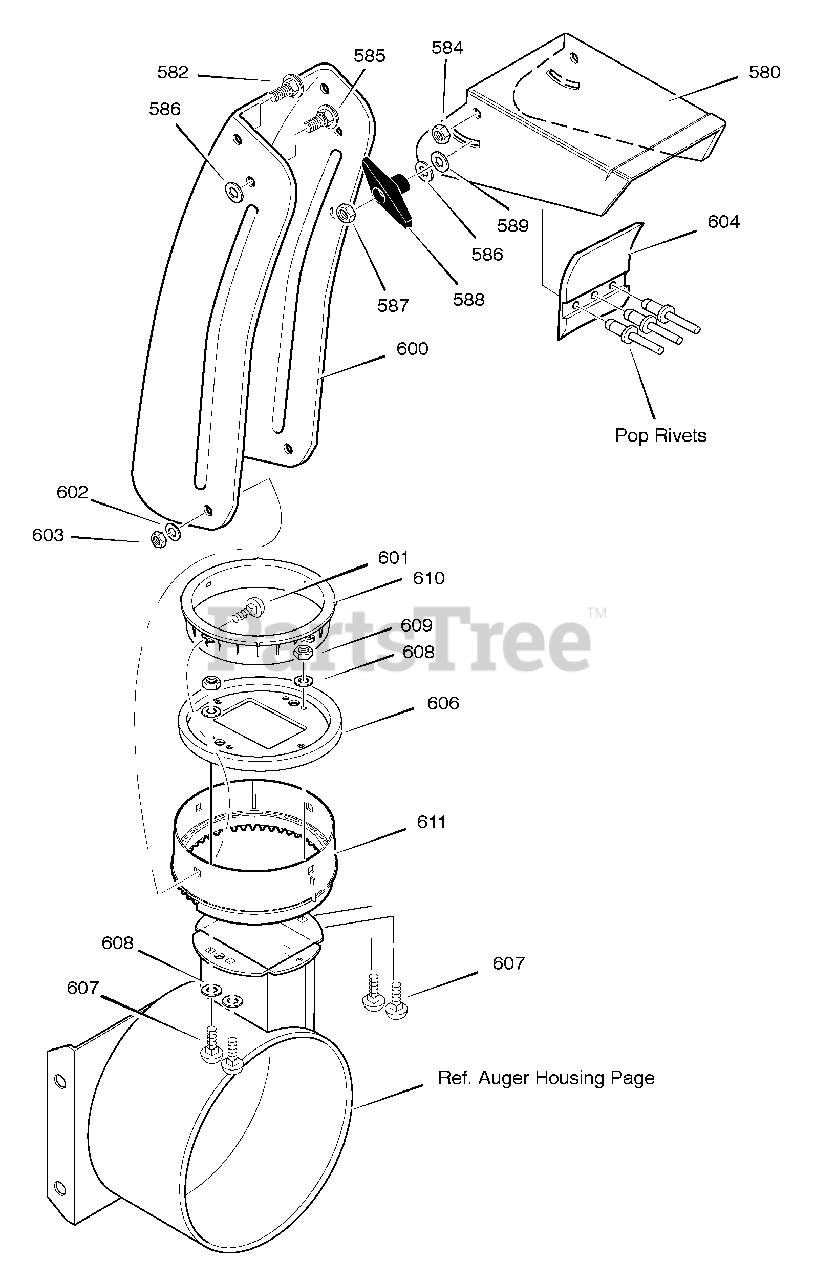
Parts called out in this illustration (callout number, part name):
580	CHUTE, UPPER
582	SCREW, 5/16-18 x 0.75
584	NUT, 5/16-18 HEX NYLOCK
585	BOLT, CAR, 5/16-18 X1.5
586	PLASTIC WASHER
587	NUT, 5/16-18 HEX
588	KNOB, T
589	PLASTIC WASHER
600	CHUTE, LOWER
601	BOLT, 5/16-18 x 1.00 CARRIAGE
602	WASHER, FLAT
603	NUT, 5/16-18 HEX NYLOCK
606	CHUTE COLLAR
607	BOLT, 1/4-20 x .75
608	WASHER, FLAT
609	NUT, 1/4-20 HEX NYLOCK
610	RETAINER, RING INNER
611	RING, OUTER CHUTE
